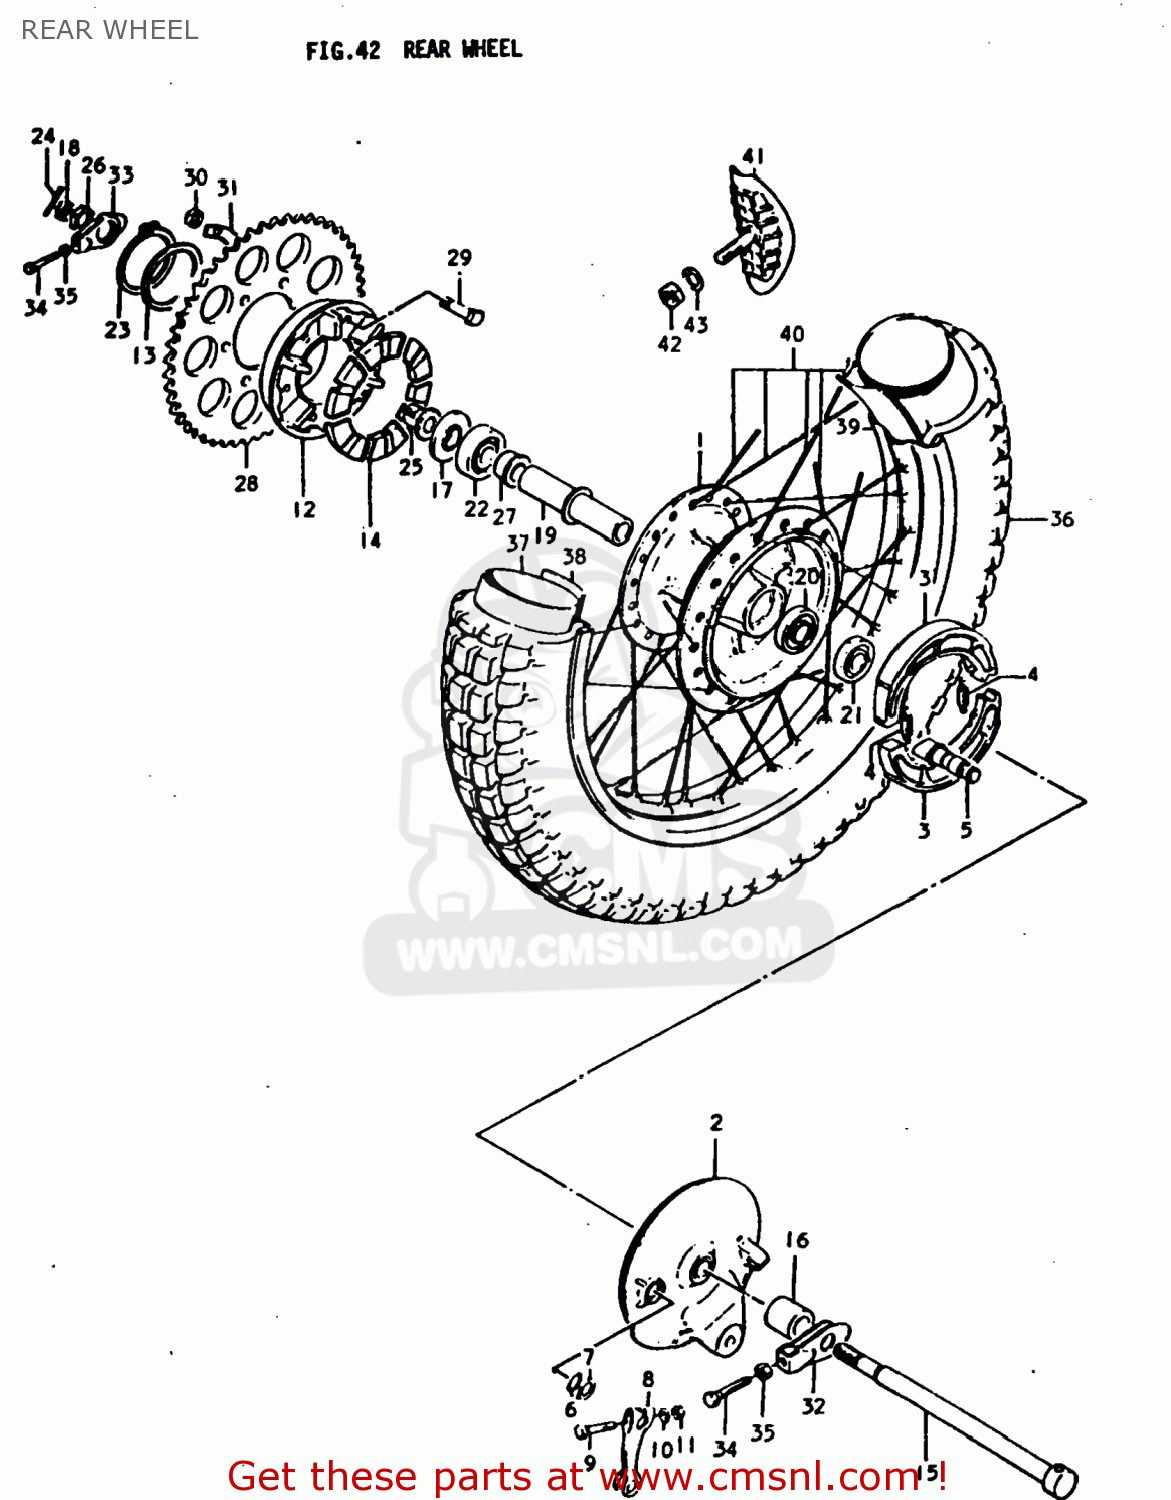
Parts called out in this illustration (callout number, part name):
1	DRUM,REAR HUB
2	PANEL,REAR HUB
3	SHOE,BRAKE
4	SPRING
5	CAM,FRONT BRAKE
6	O-RING,BOSS
7	WASHER (15X24X1.6)
8	LEVER,REAR BRAKE CAM
9	BOLT 6X40
10	WASHER
11	NUT
12	DRUM,REAR SPROCKET MOUNT
13	WASHER(62.5X77X1.6)
14	ABSORBER,RR WHEEL HUB SHOCK
15	AXLE,REAR
16	SPACER (15.2X26X20)
17	SPACER,REAR AXLE,RIGHT
18	NUT
19	SPACER,REAR HUB BEARING
20	BEARING, RH
21	OIL SEAL
22	BEARING
23	CIRCLIP
24	PIN 30X40
25	SPACER,REAR AXLE,LEFT
26	NUT
27	SPACER,REAR HUB BEARING
28	SPROCKET,REAR
29	BOLT(8X33.5)
30	NUT
31	WASHER
32	ADJUSTER,CHAIN
33	ADJUSTER,CHAIN,L
34	BOLT
35	NUT
36	TIRE
37	TUBE ASSEMBLY,WHEEL,INNER
38	PROTECTOR,WHEEL,INNER
39	RIM,WHEEL
40	SPOKE SET,REAR
41	STOPPER,BEAD
42	NUT
43	WASHER
